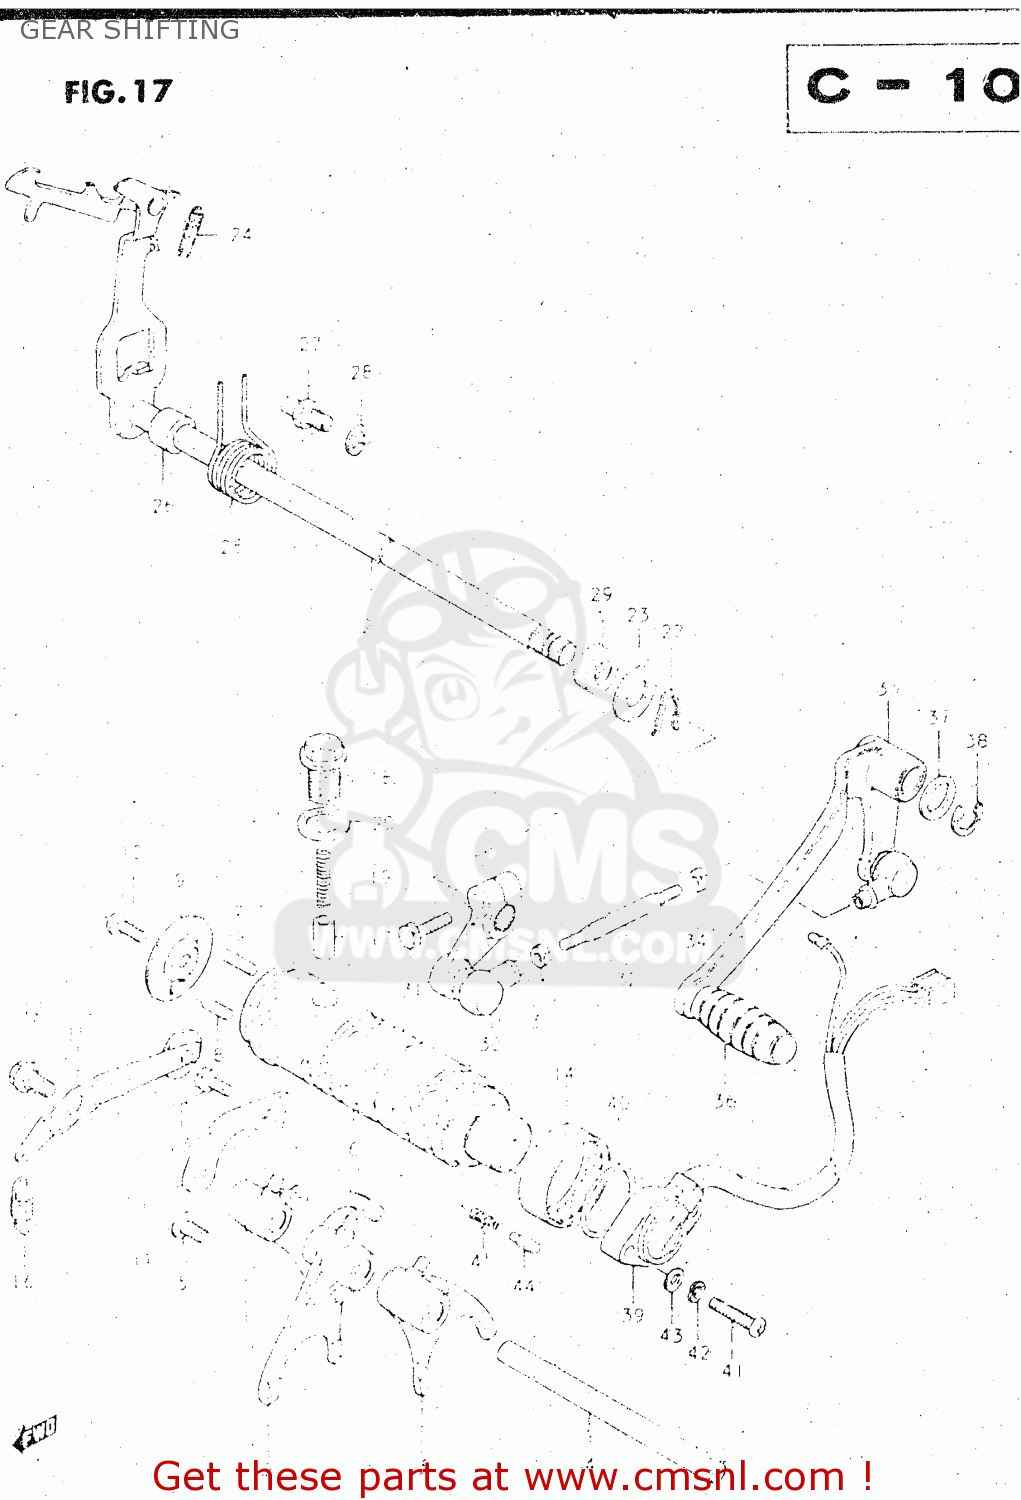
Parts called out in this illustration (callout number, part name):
1	FORK,GEAR SHIFT NO.1
2	FORK,GEAR SHIFT NO.2
3	FORK,GEAR SHIFT NO.2
4	SHAFT,GEAR SHIFT FORK
5	SCREW
6	CAM,GEAR SHIFT
7	PIN(4X18.5)
8	PIN
9	RETAINER,GEAR SHIFT CAM DR PIN
10	SCREW
11	GUIDE,GEAR SHIFTING CABLE
12	BOLT
13	BOLT
14	BEARING(40X47X12)
15	STOPPER,GEAR SHIFT CAM NO.1
16	SPRING
17	STOPPER,GEAR SHIFT CAM NO.2
18	HOLDER,GEAR SHIFT CAM STOP SPR
19	SPRING
20	GASKET(14X19.2X2) (NAS)
21	SHAFT,GEAR SHIFT
22	SPRING,RETAINER
23	WASHER (12.5X27X1.6)
24	SPRING
25	SPRING
26	SPACER(12X20X15.3)
27	STOPPER,GEAR SHIFT CAM
28	WASHER
29	OIL SEAL
30	ARM,GEAR SHIFT LINK
31	BOLT
32	ROD,GEAR SHIFT LINK
33	NUT
34	NUT
35	LEVER ASSEMBLY,GEAR SHIFTING
36	RUBBER,GEAR SHIFT PEDAL
37	WASHER(12.5X20X1)
38	CIRCLIP
39	TERMINAL BASE ASSY,GEAR SHIFT
40	O-RING (D:2.4 ID:26.2)
41	SCREW 5X20
42	LOCK WASHER
43	WASHER
44	PIN(5X15.5)
45	SPRING
